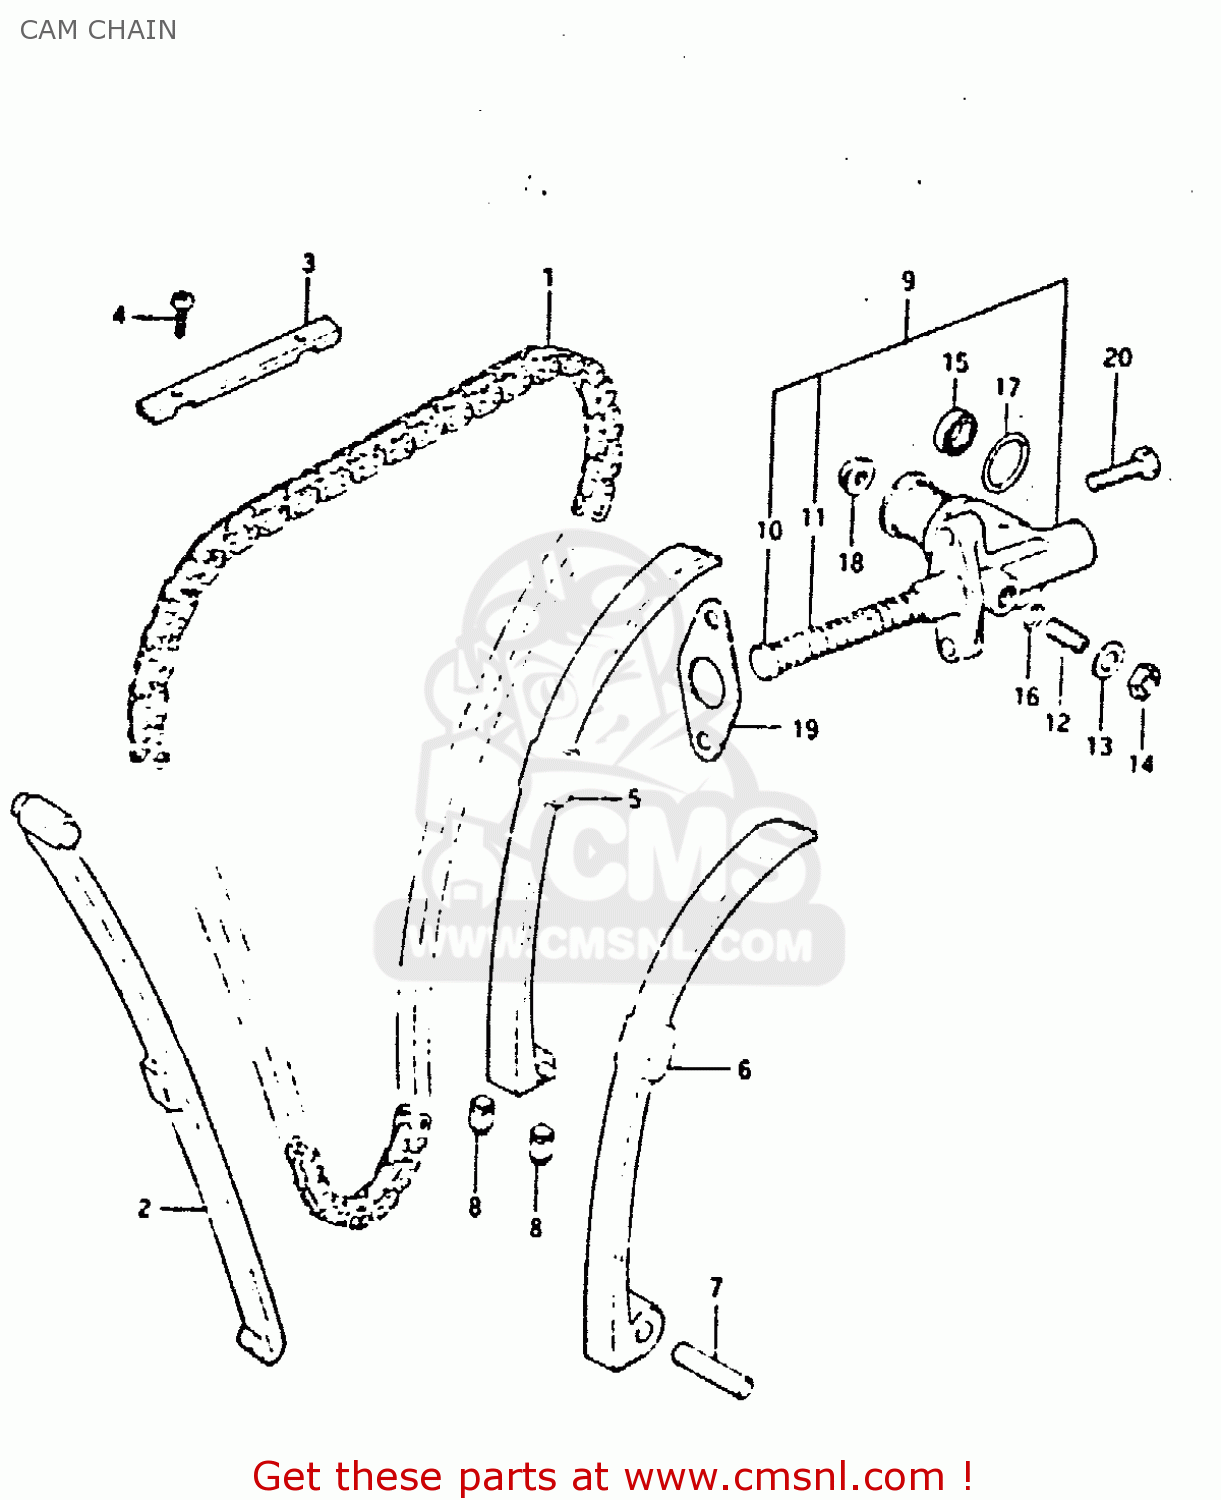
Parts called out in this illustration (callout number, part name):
1	CHAIN,CAMSHAFT DRIVE(120L)
2	GUIDE,CAM CHAIN
3	GUIDE,CAM CHAIN
4	SCREW
5	TENSIONER,CAM CHAIN
6	TENSIONER,CAM CHAIN
7	PIN
8	CUSHION,CAM CHAIN TENSIONER
9	ADJUSTER ASSEMBLY,TENSIONER
10	ROD,PUSH
11	SPRING
12	SCREW,TENSIONER ADJUST
13	WASHER,8.5X16X
14	NUT
15	SEAL,OIL(10X16X4)
16	O RING(D:1.9,ID:5.7)
17	O RING(D:2.4,ID:20.8)
18	NUT
19	GASKET,TENSIONER ADJUSTER (MCA)
20	SCREW
